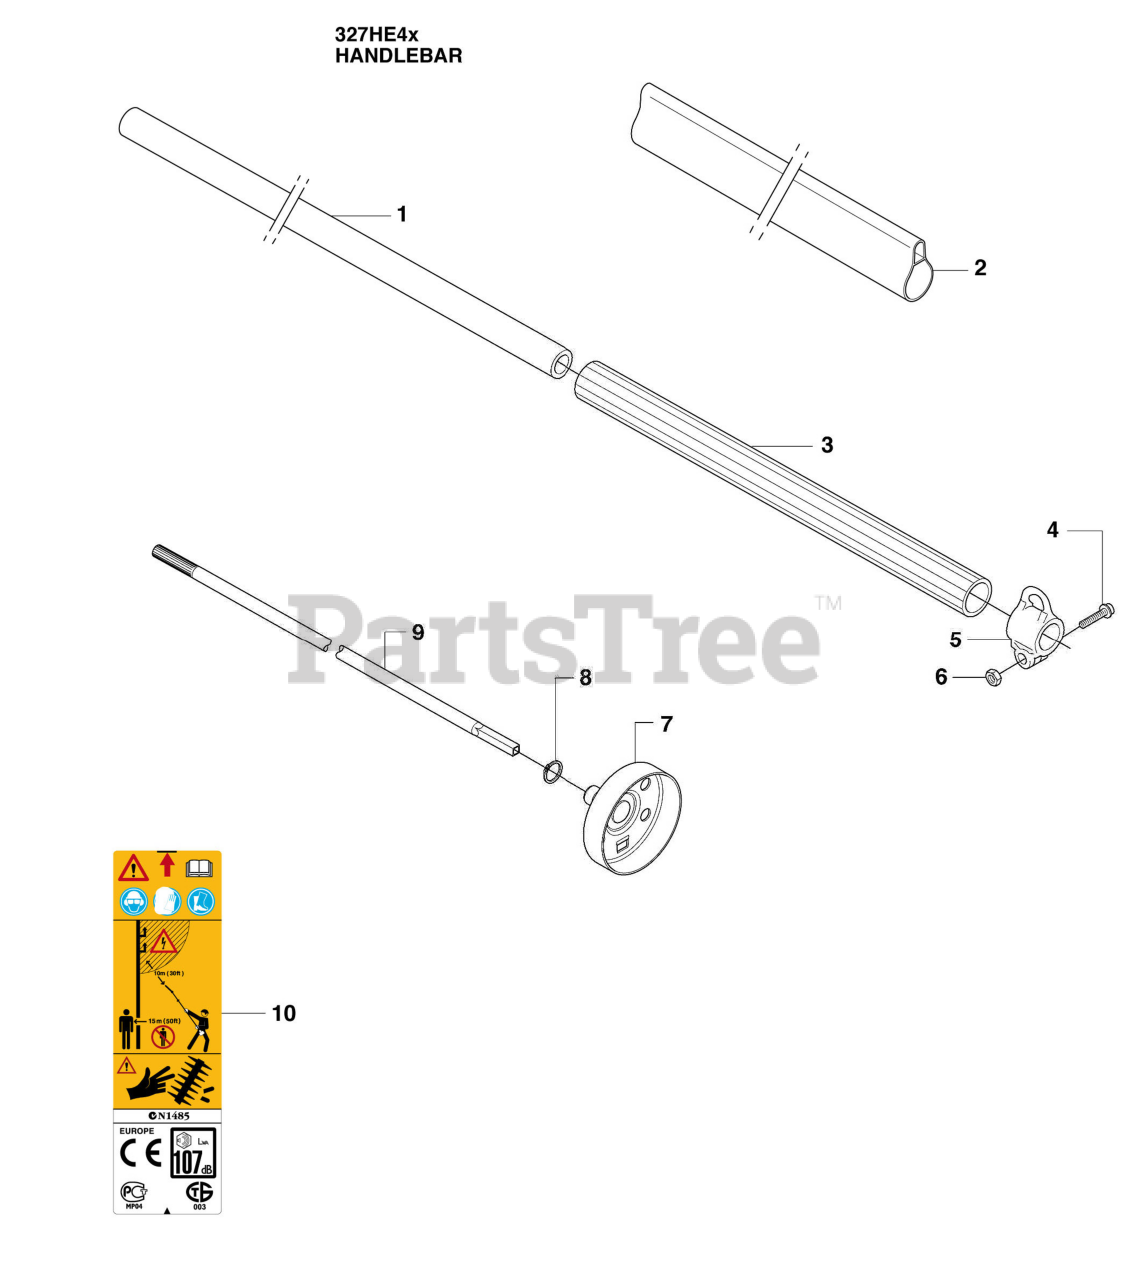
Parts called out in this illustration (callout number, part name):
1	Drive Tube Assembly
2	PROTECTOR
4	Screw, M5 X 16 Ms Hsc Ih X
5	Harness Holder
6	Hex Nut, M5 X .80 DIN
7	Clutch Drum
9	Drive Shaft
10	DECAL
